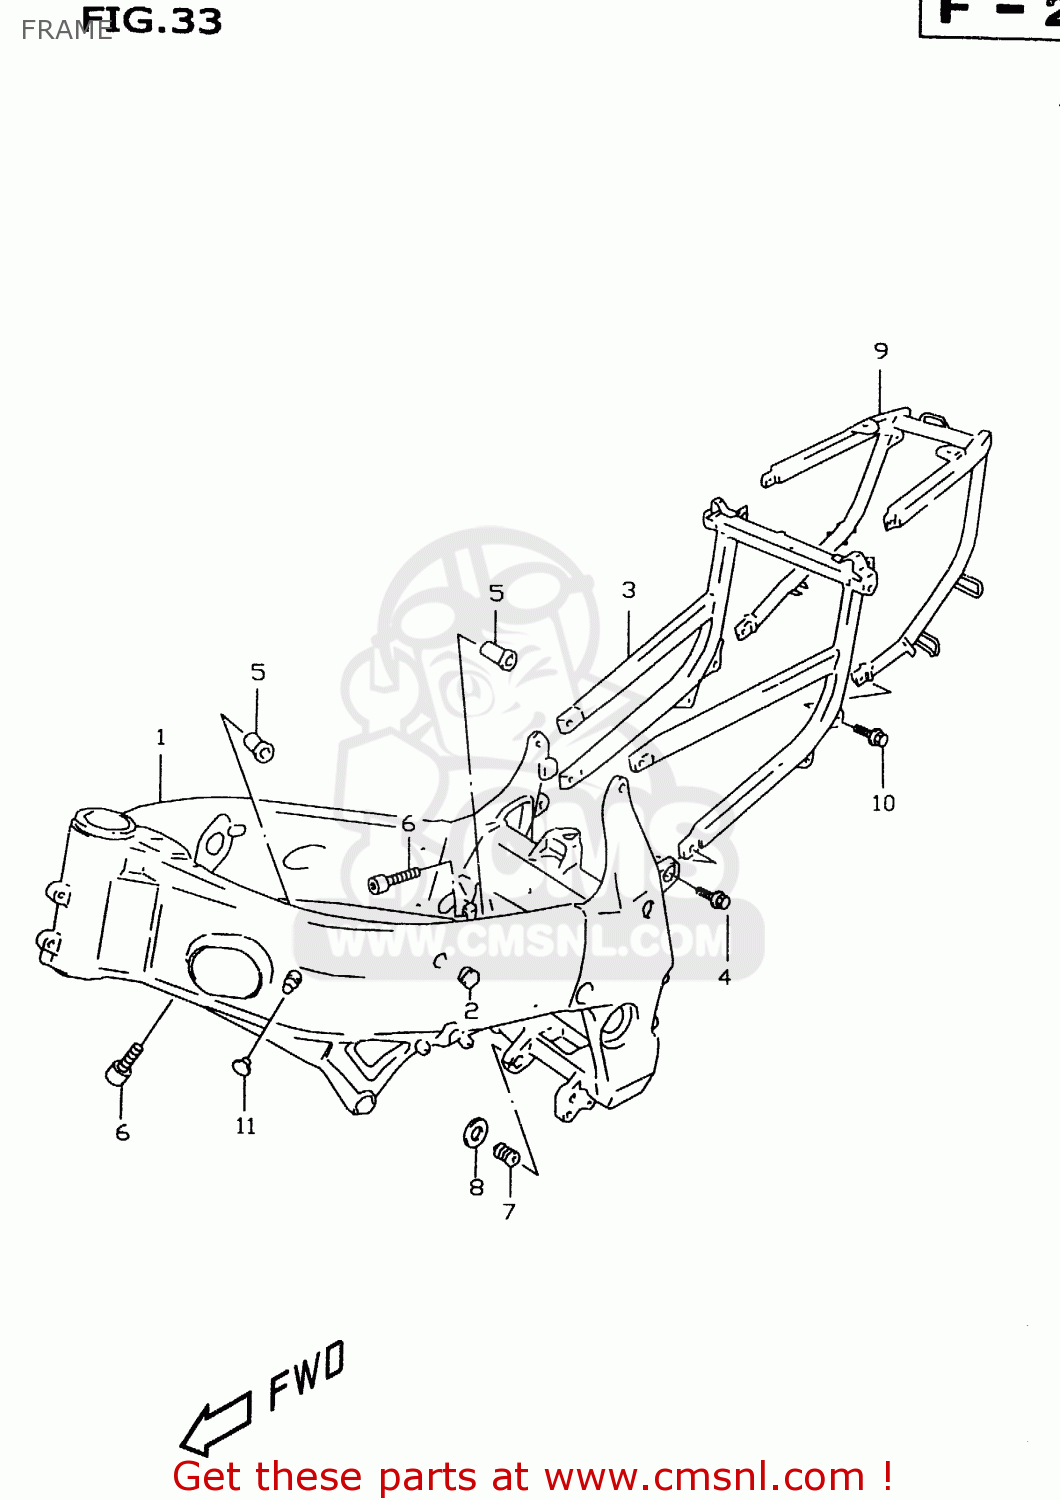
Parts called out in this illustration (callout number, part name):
1	FRAME
2	CAP,TANK RAIL
3	RAIL,SEAT
4	BOLT(10X30)
5	SPACER,ENGINE MOUNTING
6	BOLT
7	BOLT,CRANKCASE ADJUST
8	NUT,CRANKCASE ADJUST
9	GRIP,RR
10	BOLT
11	CAP
